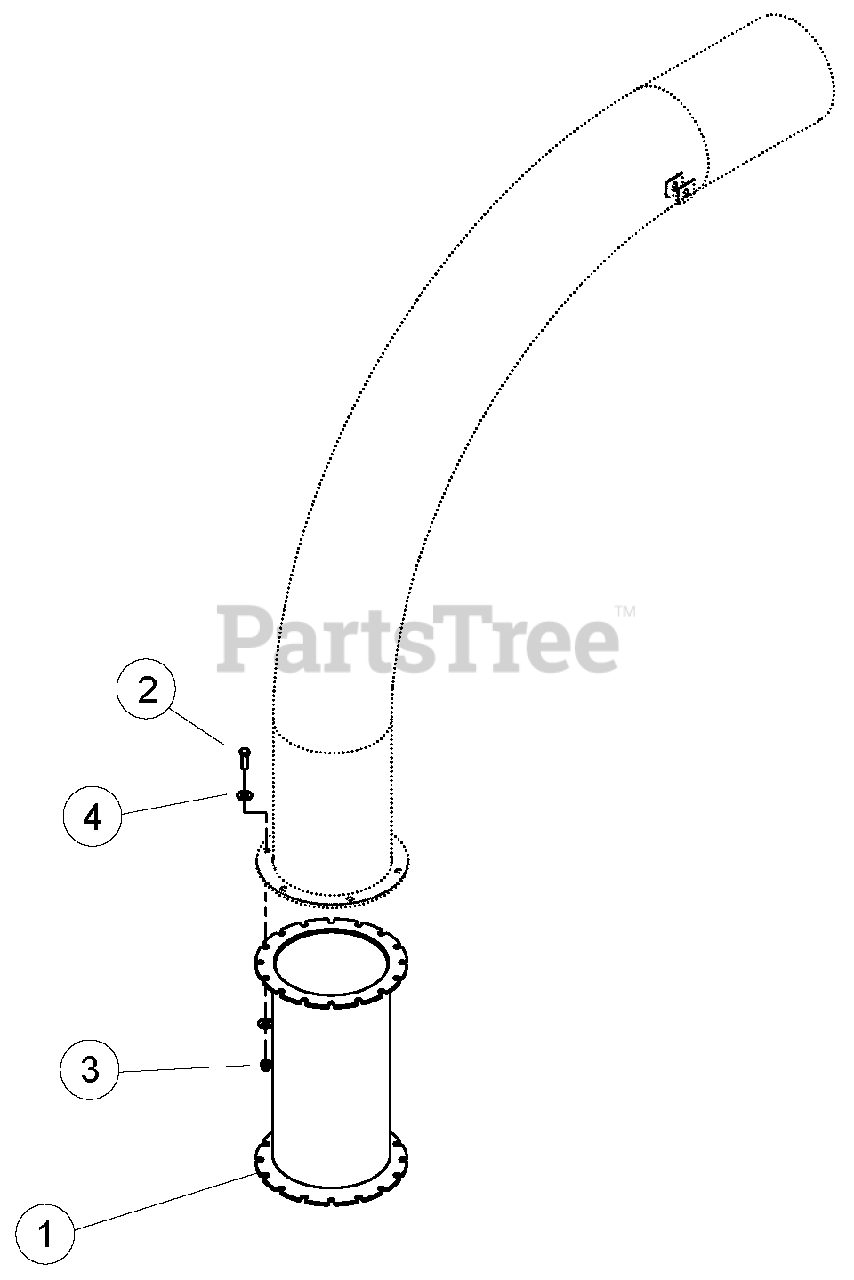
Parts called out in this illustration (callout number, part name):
1	WELDMENT, CHUTE EXTENSION
2	BOLT, 3/8 X 1-1/4"HHCS GR5 ZP
3	NUT, 3/8" NE NYLOCK ZP
4	WASHER, 3/8" FLAT ZP
